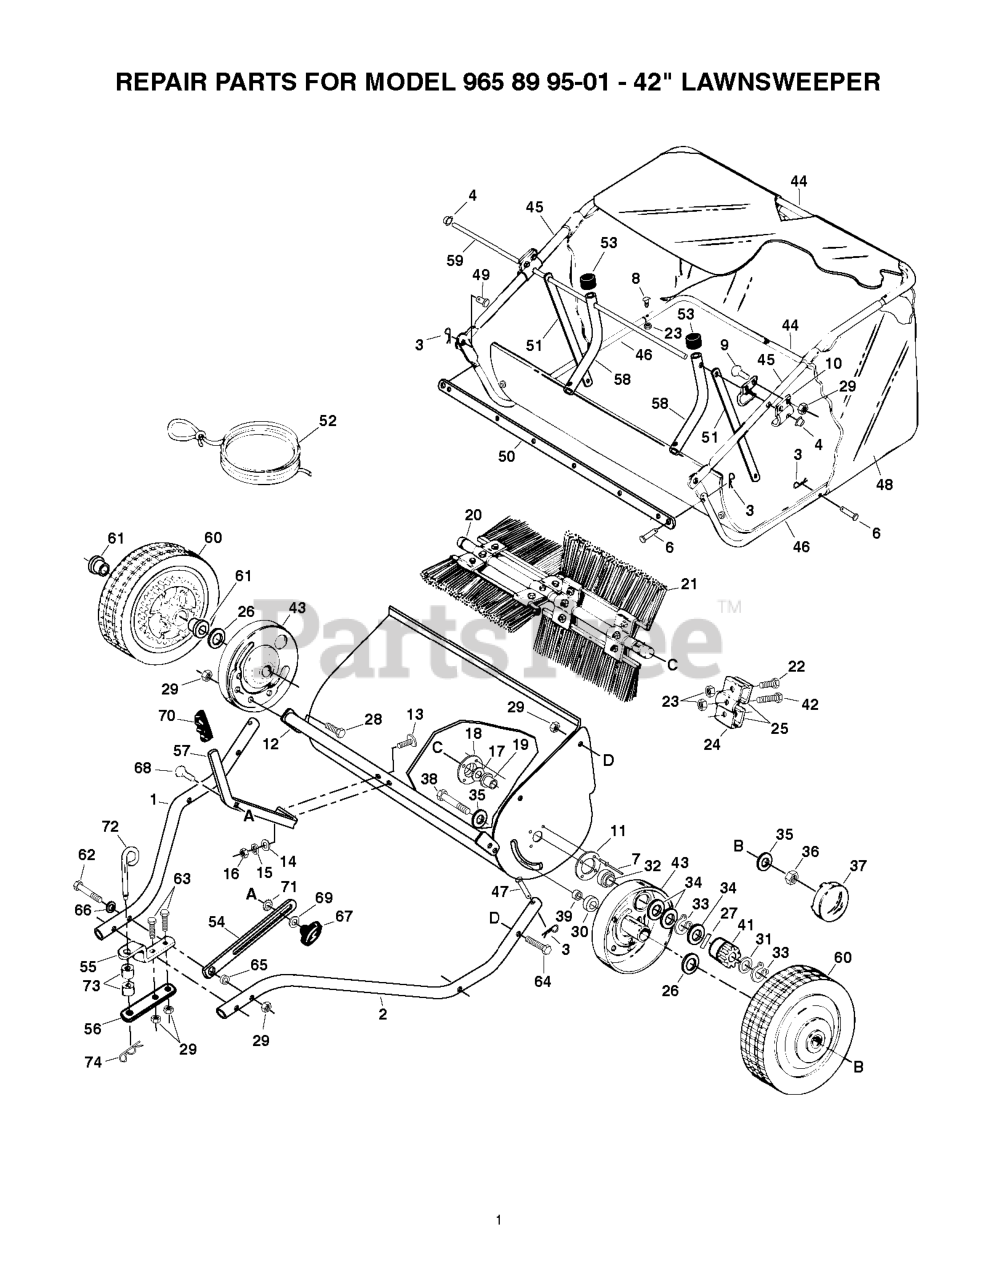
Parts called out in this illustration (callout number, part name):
2	TUBE, L.H.
3	Pin, Hair Cotter 3/32" #3
10	HOPPER MOUNTING CLAMPS
13	Bolt, Cv. Hd. 5/16-18 x 1-5/8" Lg.
18	BEARING RETAINER
24	BRUSHRETAINER DOUBLE
25	BRUSH RETAINER SINGLE
26	Washer, Flat 1-1/8" x .78" x .025"
33	Retaining Ring .594" I.D.
34	SHIM WASHER
39	Spacer 13/32" x 5/8" x 3/16"
47	PIN CLEVIS 1/4
48	ASS'Y HOPPER BAG (22 CU. FT)
50	STRAP BAG FRAME
55	Bracket, Hitch
57	Handle, Height Adjustment
58	TUBE.BAG.ARM.AGRI-FAB
60	WHEEL
62	Bolt, Hex 5/16-18 x 3" Lg.
64	SCREW
67	Knob, Wing 5/16-18 Thread
70	Rubber Grip
71	WASHER, TOOTH LOCK
72	Pin, Hitch
73	Hitch Adjustment Tube
